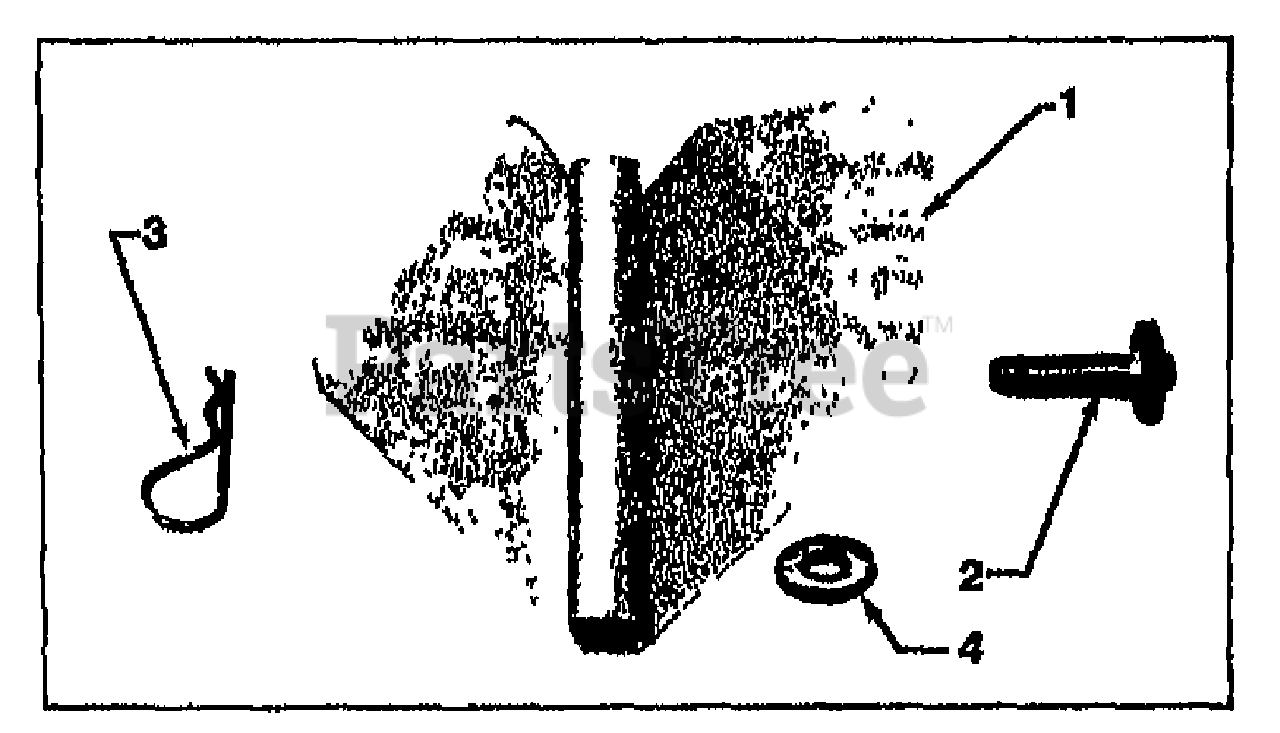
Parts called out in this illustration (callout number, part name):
1	CULTIVATOR FURROWER (INCL. 9370 & 9368)
2	PIN-LOCK ZP
3	PIN-HITCH ZP
4	WASHER-FLAT 3/8 SAE
